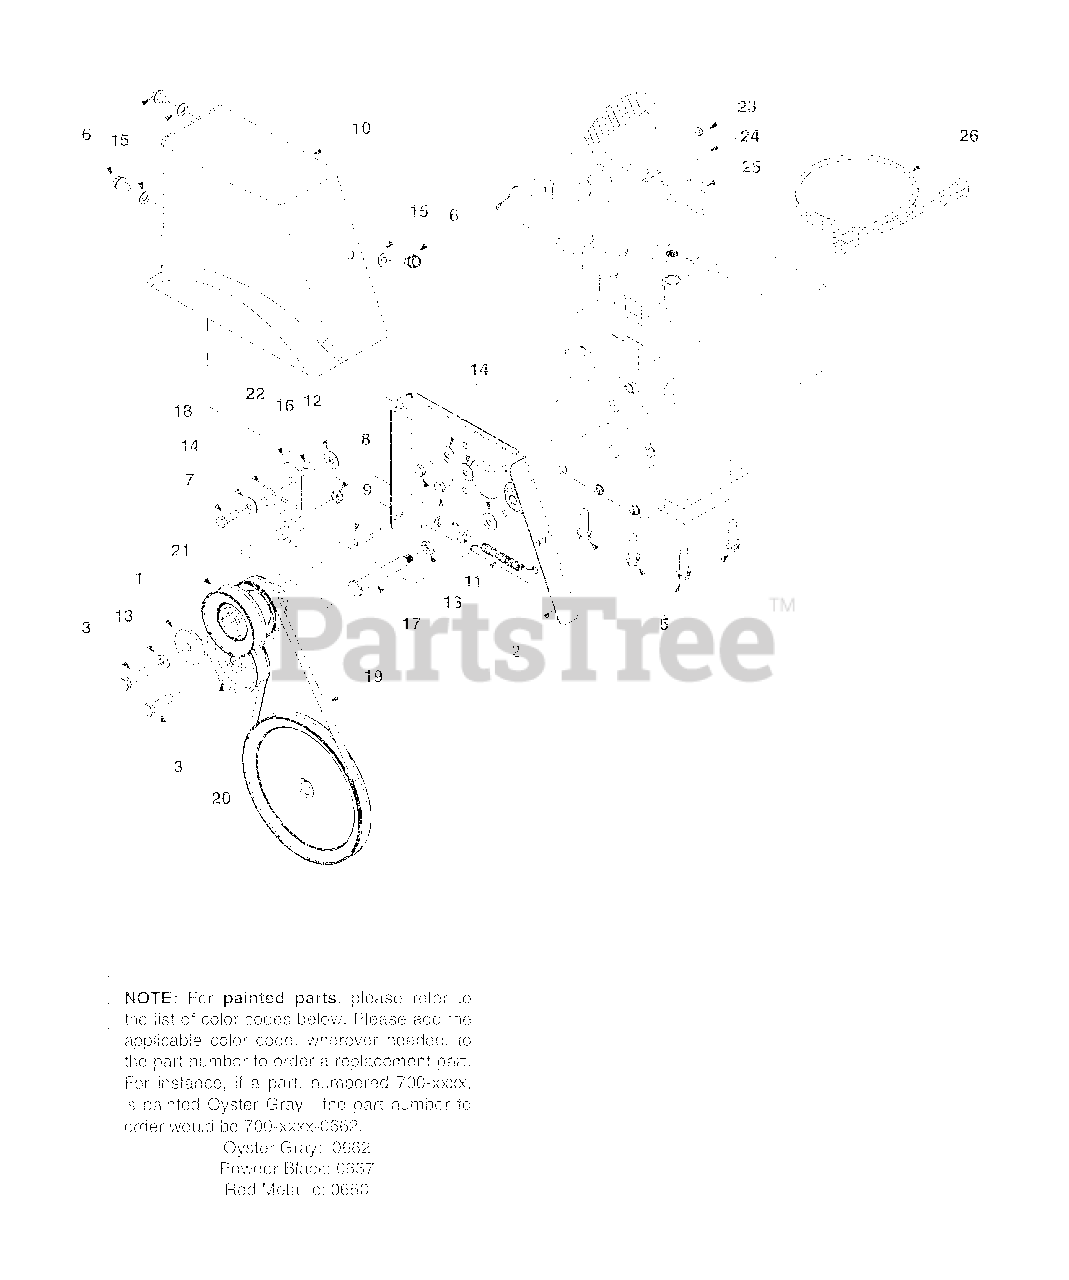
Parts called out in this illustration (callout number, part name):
4	Hex Screw 5/16-24 x .625"
5	Tf Sems Screw
6	Tf Screw 5/16-18 x 0.5"
7	Hex Lock Screw 5/16-24 x .875"
10	Belt Cover
11	Extension Spring
14	Beleville Washer
16	Grease
17	Shoulder Screw
18	Shoulder Spacer
19	V-Belt
21	Double Pulley
22	Idler Bracket
23	Hex Lock Nut: 1/4-20
26	Extension Cord: 110V, 3-prong
